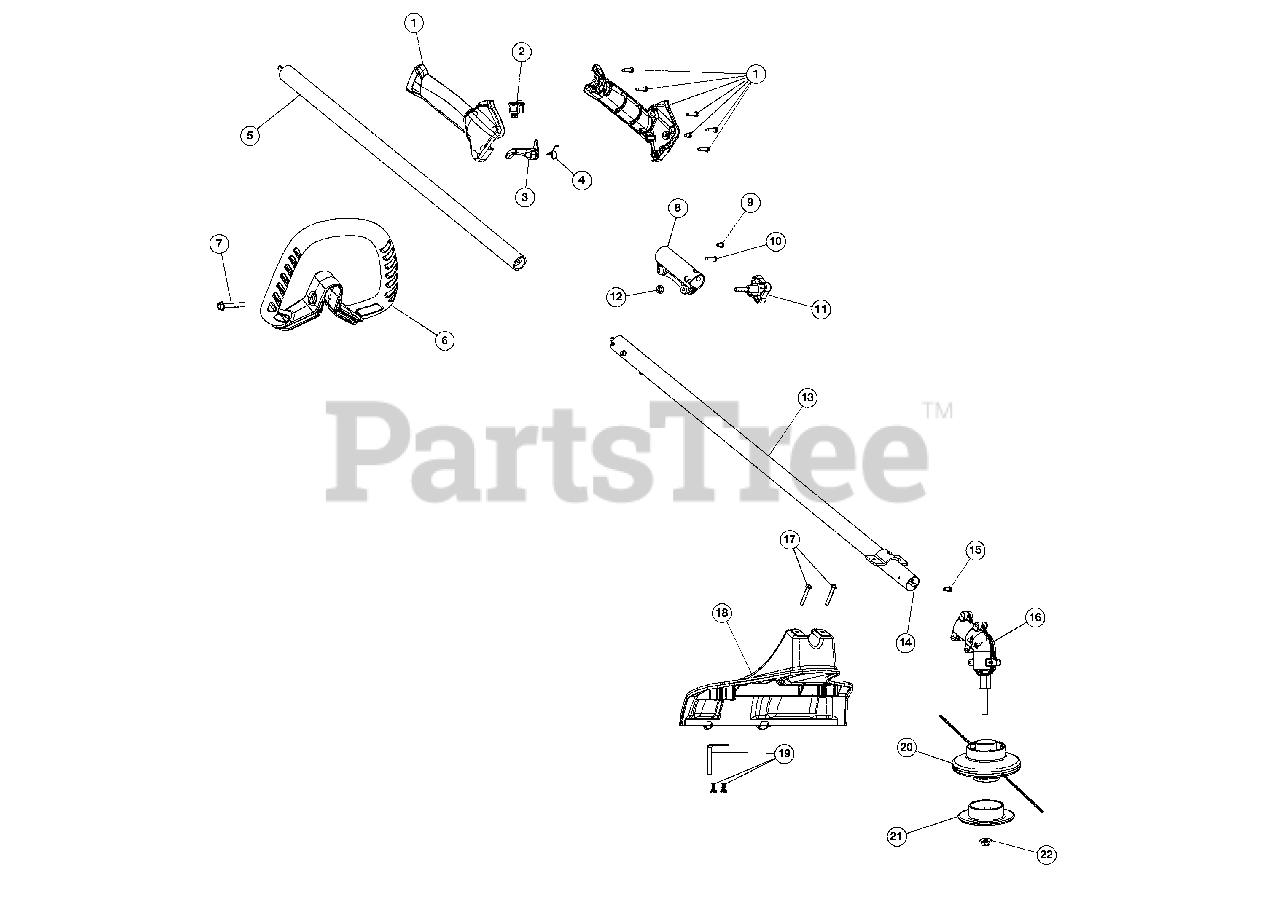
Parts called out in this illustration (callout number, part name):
1	Throttle Housing Assembly (Incl. 2-4)
3	Throttle Trigger
4	Throttle Trigger Spring
5	Upper Shaft Housing Assembly
6	D-Handle (Incl. 7)
7	D-Handle Hardware
8	Split Boom Coupler (Incl. 9-12)
9	Anti-Rotation Screw
11	Adjustment Knob
12	Knob Retainer Nut
13	Lower Shaft Housing Assembly
14	Lower Flexible Drive Shaft
15	Anti-Rotation Screw
16	Gear Box Assembly (Incl. 15 & 20-22)
17	Shield Mounting Screws
18	Shield Assembly (Incl. 17 & 19)
19	Blade Assembly
20	Cutting Head Assembly (Incl. 21 & 22)
21	Glide Cap
22	Lock Nut
